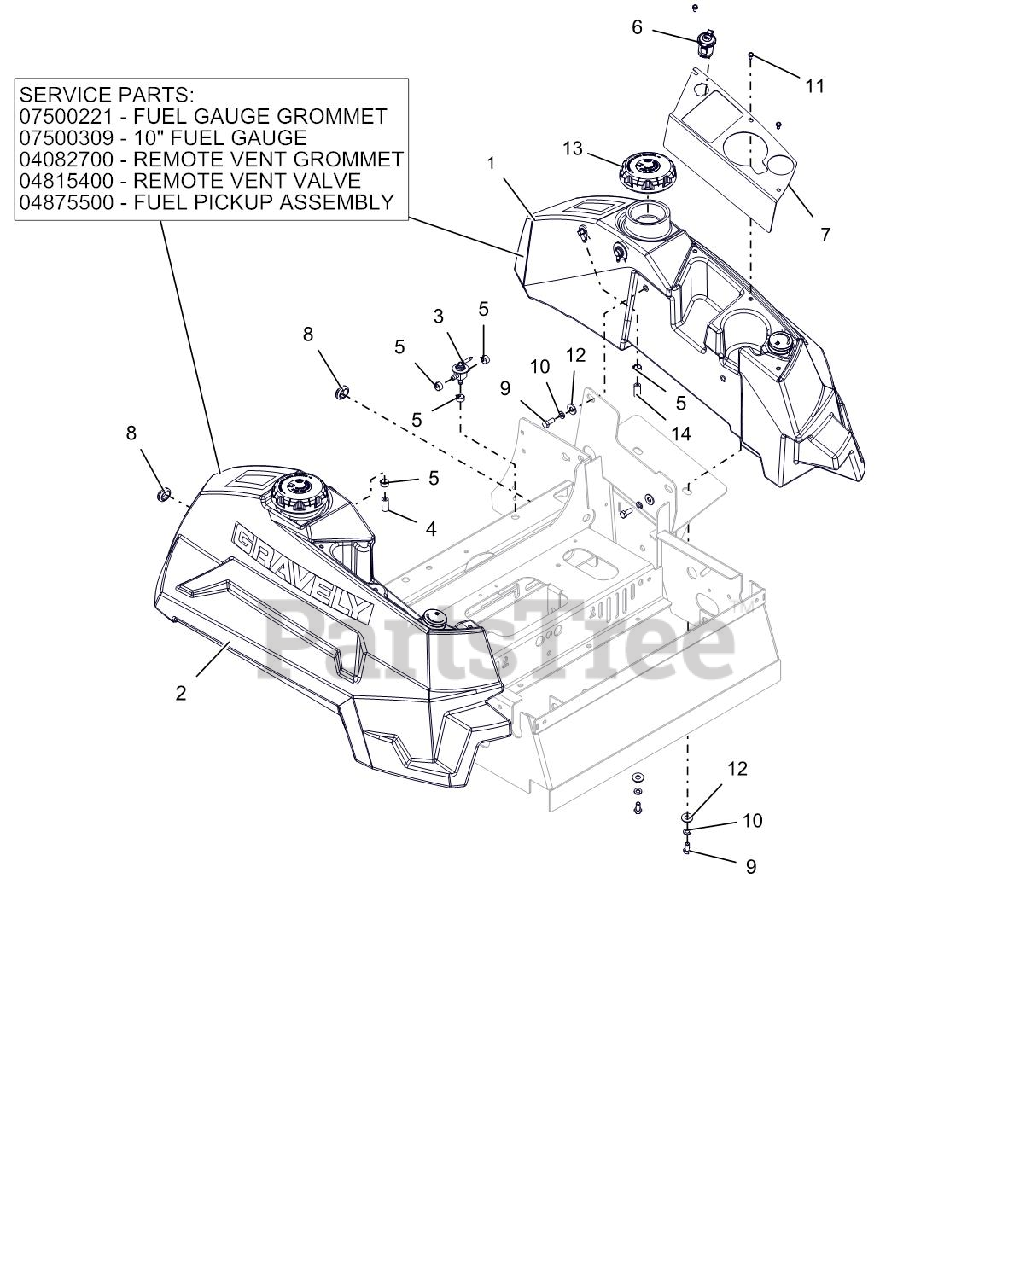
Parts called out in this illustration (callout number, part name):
1	ASM, PT200/400 LH FUEL TANK
2	ASM, PT200/400 RH FUEL TANK
3	VALVE - FUEL
4	HOSE, .25 LOW-PERM BULK GAS
5	CLAMP, FUEL LINE
6	PORT, 12 VOLT POWER
7	CUP HOLDER/POCKET PLATE - RED
8	GROMMET,RUBBER 5/8 ID/1.13 OD
9	@BLT-HEX .31-18X.75 GR5 YWZC
10	@WSHR-LK .31X.078 REG YWZC
11	SCR-MCH 10-24X.38 HWHSTAINLESS
12	@WSHR-FL-STL.38X.875X.083 YWZC
13	CAP, FUEL NONVENT AUTOLOCK
14	HOSE, .25 LOW-PERM BULK GAS
15	GROMMET, FUEL GAUGE
16	GAUGE, REMOTE FUEL SEALED 10"
17	GROMMET, REMOTE VENT NITRILE
18	VALVE, 2-WAY
19	ASSM,LRG TANK FUEL PICKUP LINE
